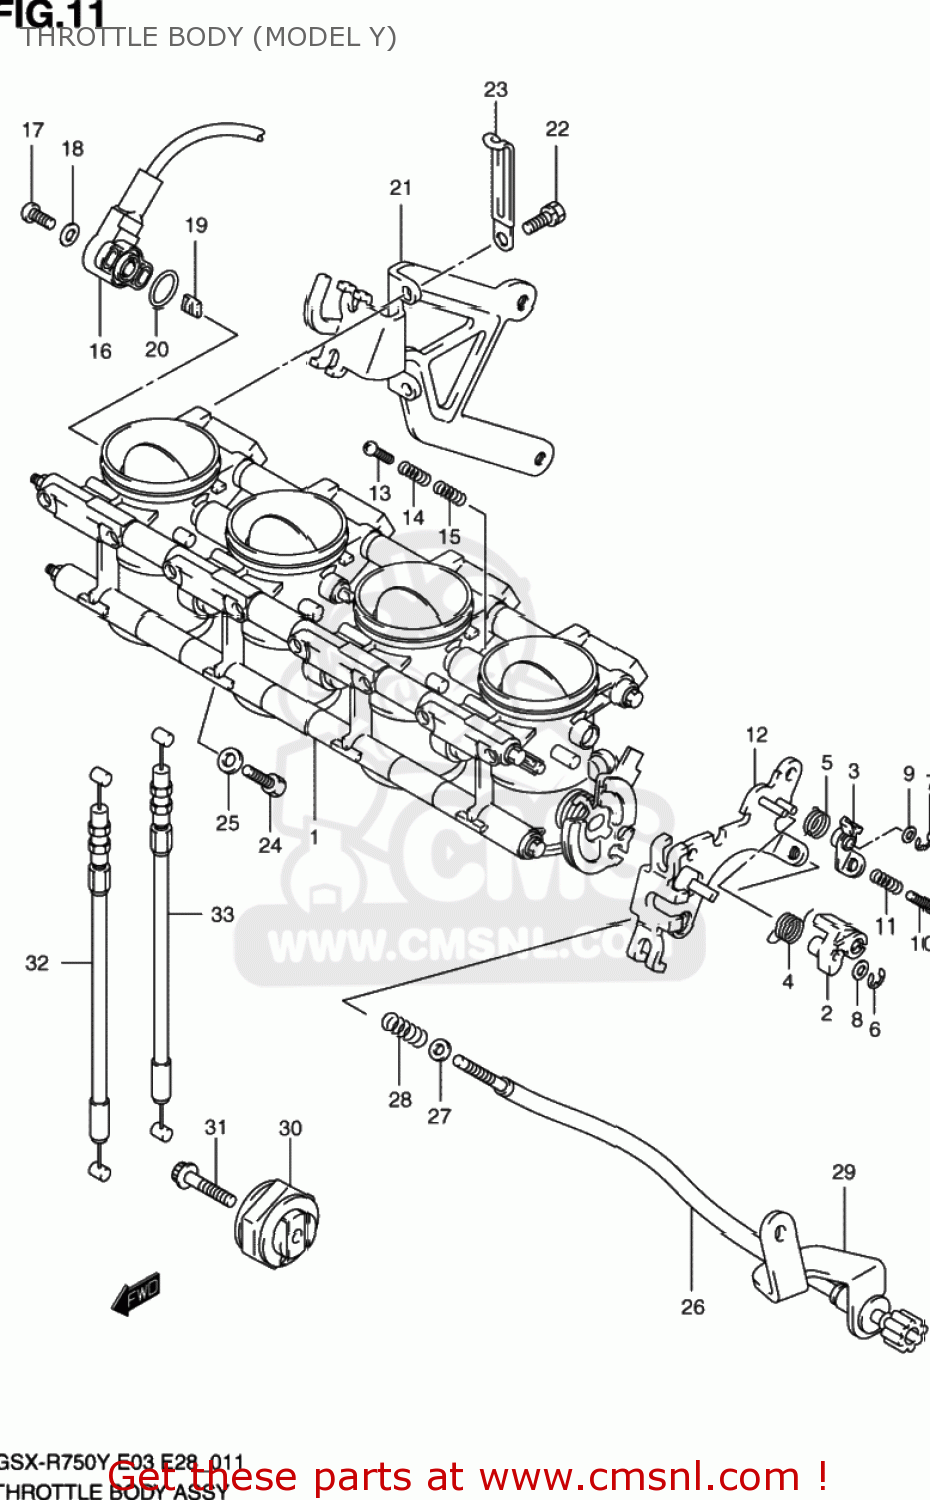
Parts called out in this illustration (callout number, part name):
1	BODY SET,THROTTLE
2	LEVER,LINK
3	LINK,LEVER
4	SPRING
5	SPRING
6	E CLIP
7	E CLIP
8	WASHER
9	WASHER
10	SCREW,STOP
11	SPRING
12	PLATE,STAY
13	SCREW
14	SPRING
15	SPRING
16	SENSOR ASSY,THROTTLE
17	SCREW
18	WASHER
19	COLLAR
20	O RING
21	PLATE,STAY
22	BOLT
23	CLAMP
24	BOLT
25	PACKING (NAS)
26	SCREW,STOP
27	WASHER
28	SPRING
29	BRACKET,IDLE ADJUST
30	PULLEY,CONTROLLER
31	BOLT
32	CABLE,THROTTLE ACTUATOR OPEN
33	CABLE,THROTTLE ACTUATOR CLOSE
